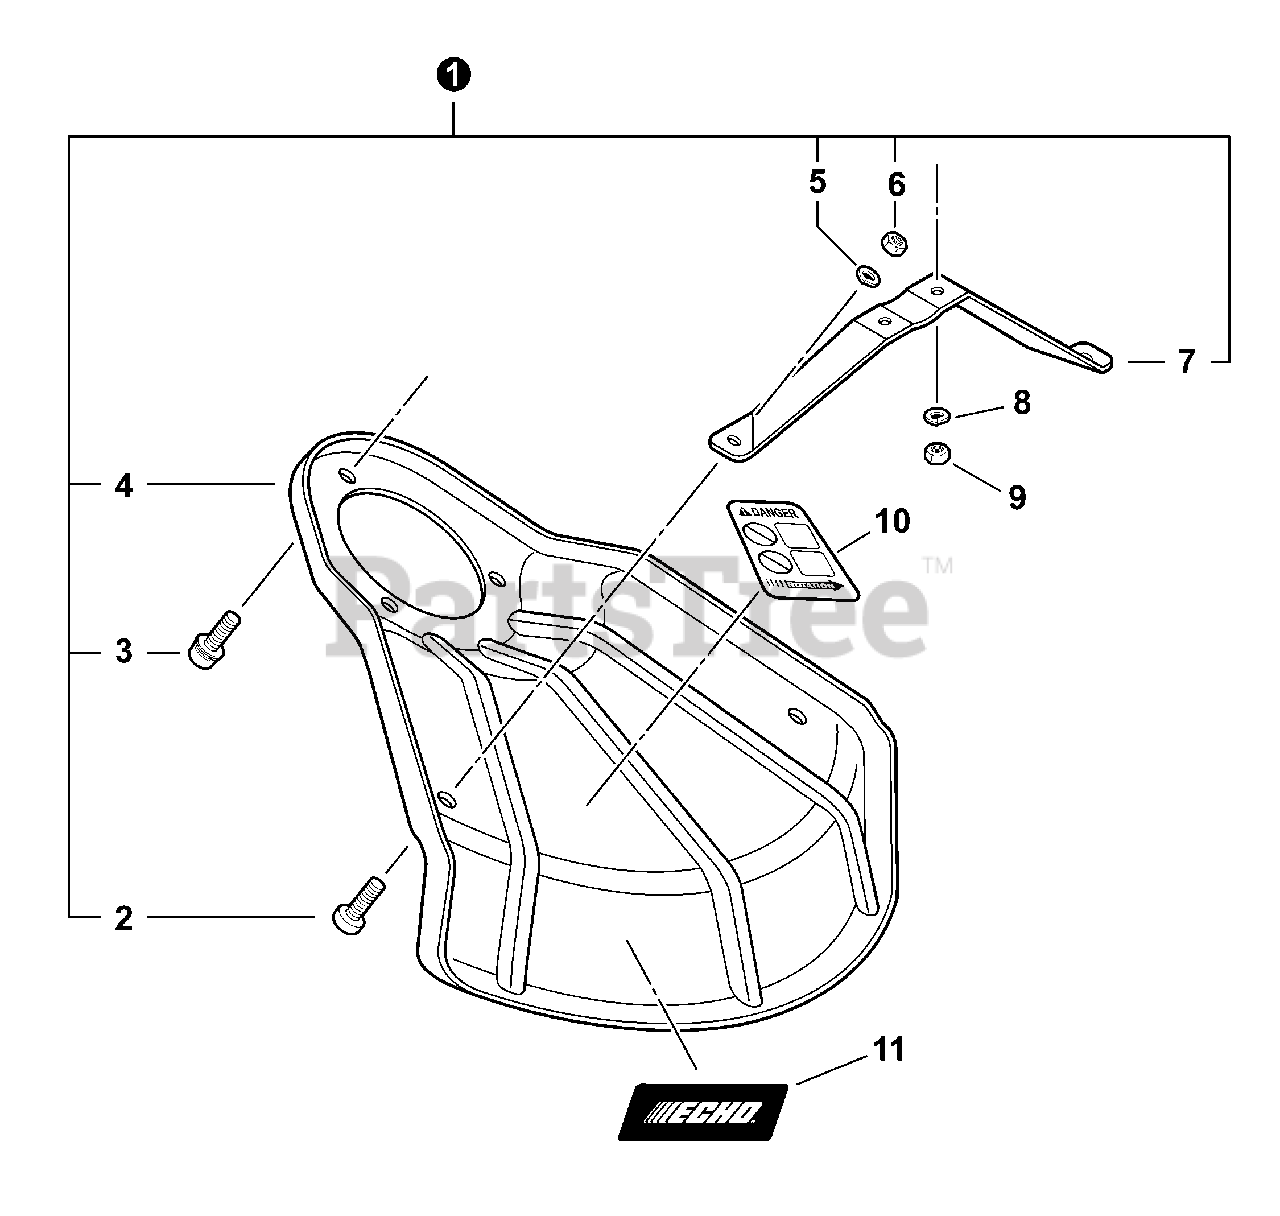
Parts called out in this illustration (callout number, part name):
1	DEBRIS SHIELD KIT - METAL
2	SCREW - 5×8
3	SCREW - 5×10
4	SHIELD, DEBRIS - METAL
5	LOCKWASHER - 5
7	BRACKET, SHIELD
8	LOCKWASHER - 5
10	LABEL - DANGER
11	LABEL - ECHO
